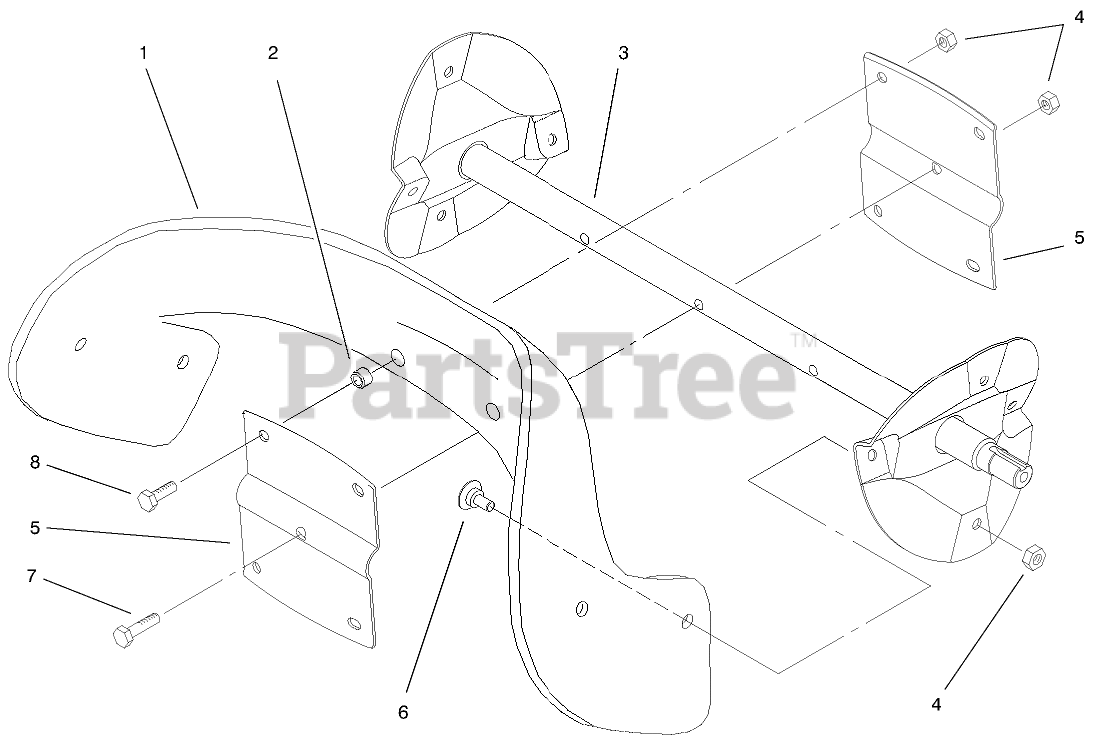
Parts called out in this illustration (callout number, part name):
1	Blade-Rotor
2	SPACER-BLADE, ROTOR
3	Wa-Rotor
4	NUT-LOCK, NI
5	Rotor
6	SCREW
7	SCREW-HH
8	SCREW-HH
